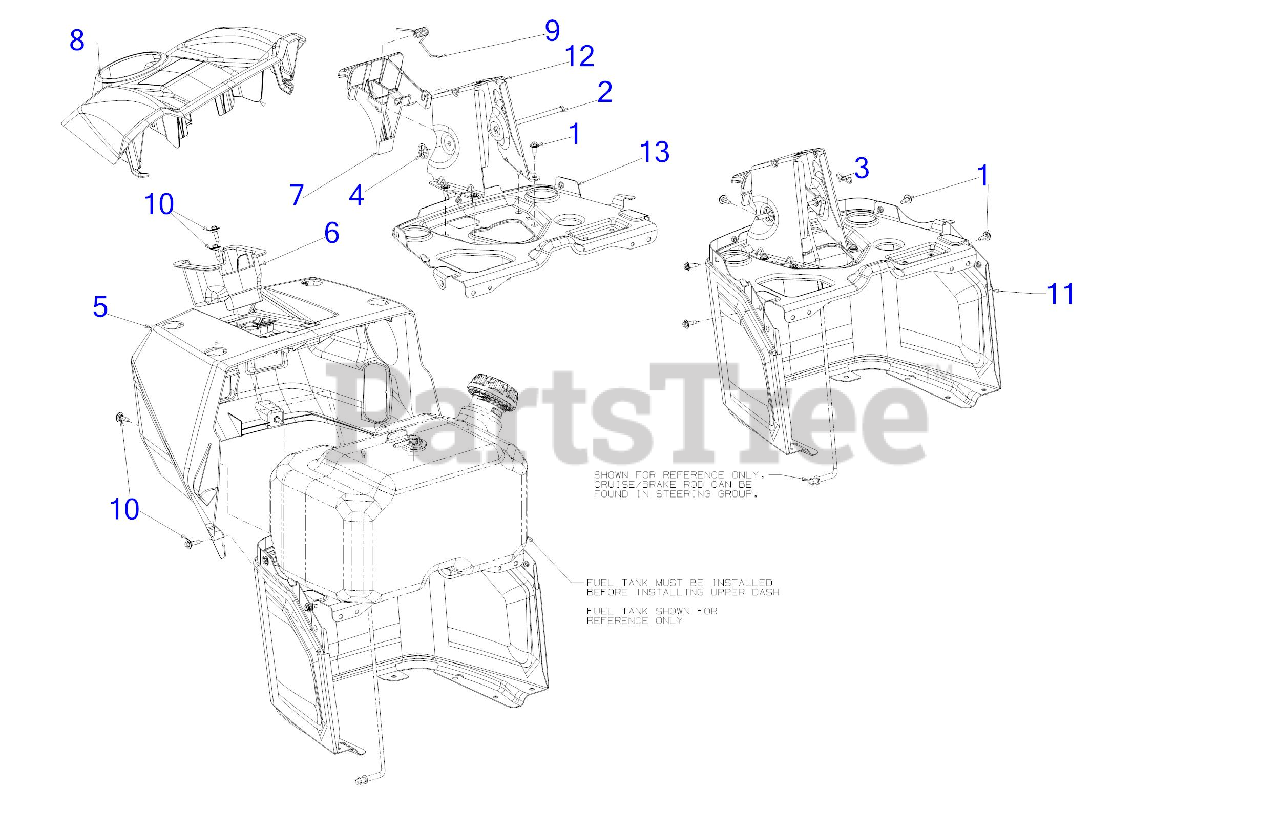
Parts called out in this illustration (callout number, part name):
1	SCREW M6-1 x .625
2	HINGE PIN .25 x 4.50
3	BOW TIE COTTER PIN 1/4-5/16
4	PUSH ON NUT
5	UPPER DASH
6	STEERING SHAFT BEARING
7	CRUISE/BRAKE DASH LEVER
8	UPPER DASH CAP
9	TORSION SPRING .330 ID
10	SHOULDER SCREW M6-1 .368 X.115
